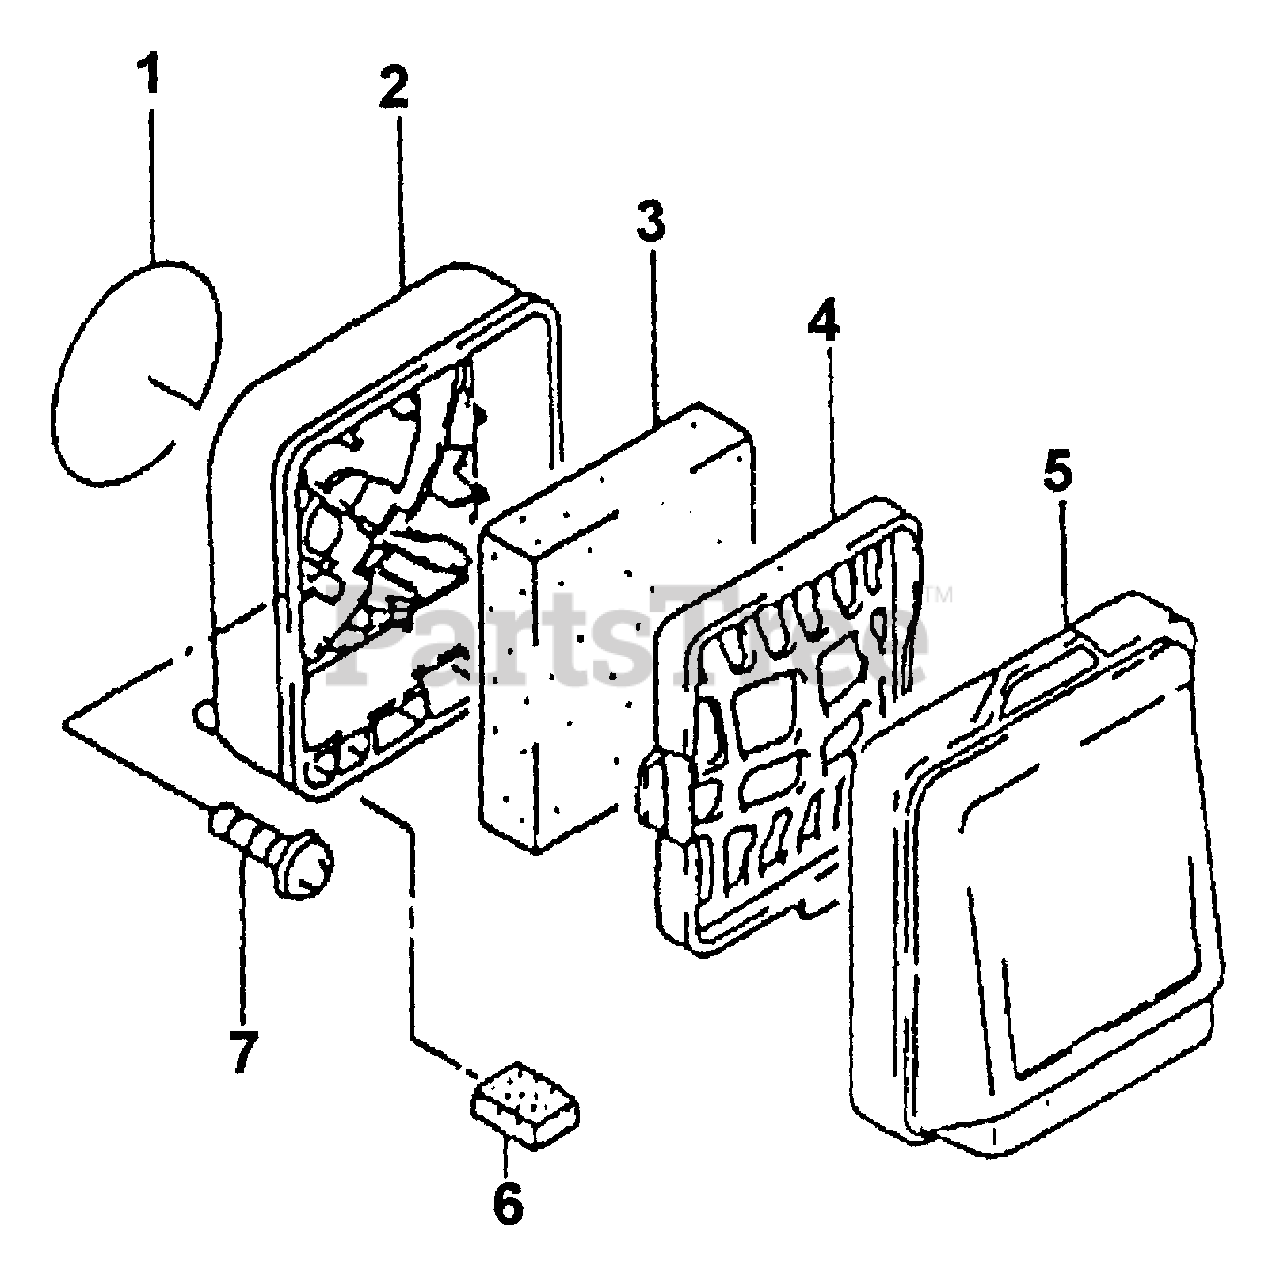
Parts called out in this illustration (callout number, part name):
3	ELEMENT (LARGE)
6	ELEMENT (SMALL)
7	SCREW
